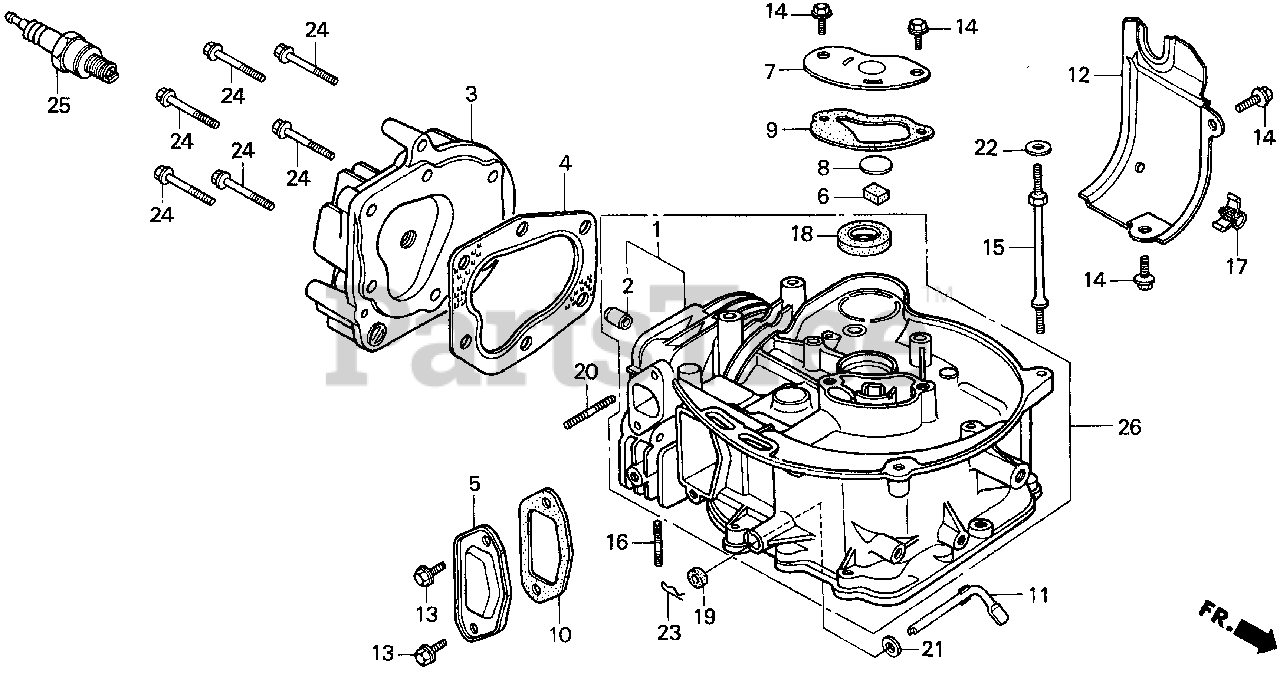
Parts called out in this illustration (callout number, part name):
1	CYLINDER
2	GUIDE, VALVE (OVER SIZE)
3	CYLINDER HEAD
4	GASKET, CYLINDER HEAD
5	COVER, TAPPET ROOM
6	FILTER, BREATHER
7	CAP, BREATHER CHAMBER
8	VALVE, BREATHER
9	GASKET, BREATHER CAP
10	GASKET, TAPPET COVER
11	SHAFT, GOVERNOR ARM
13	BOLT, FLANGE (5X10) Use from Engine SN 2327377.
14	BOLT, FLANGE (6X12) (CT200)
15	BOLT, SPECIAL STUD
16	BOLT, STUD (6X28) (CT200)
17	CLIP, TUBE (7MM)
18	OIL SEAL (17X30X6) (NOK)
19	OIL SEAL (5X10X4)
20	BOLT 2, STUD (5X25)
21	WASHER, PLAIN (5MM)
22	WASHER, PLAIN (5MM)
23	PIN, LOCK (8MM)
24	BOLT, FLANGE (6X35)
25	SPARK PLUG (BMR4A) (NGK)
25	SPARK PLUG (W14MR-U) (DENSO)
26	CYLINDER ASSY.
